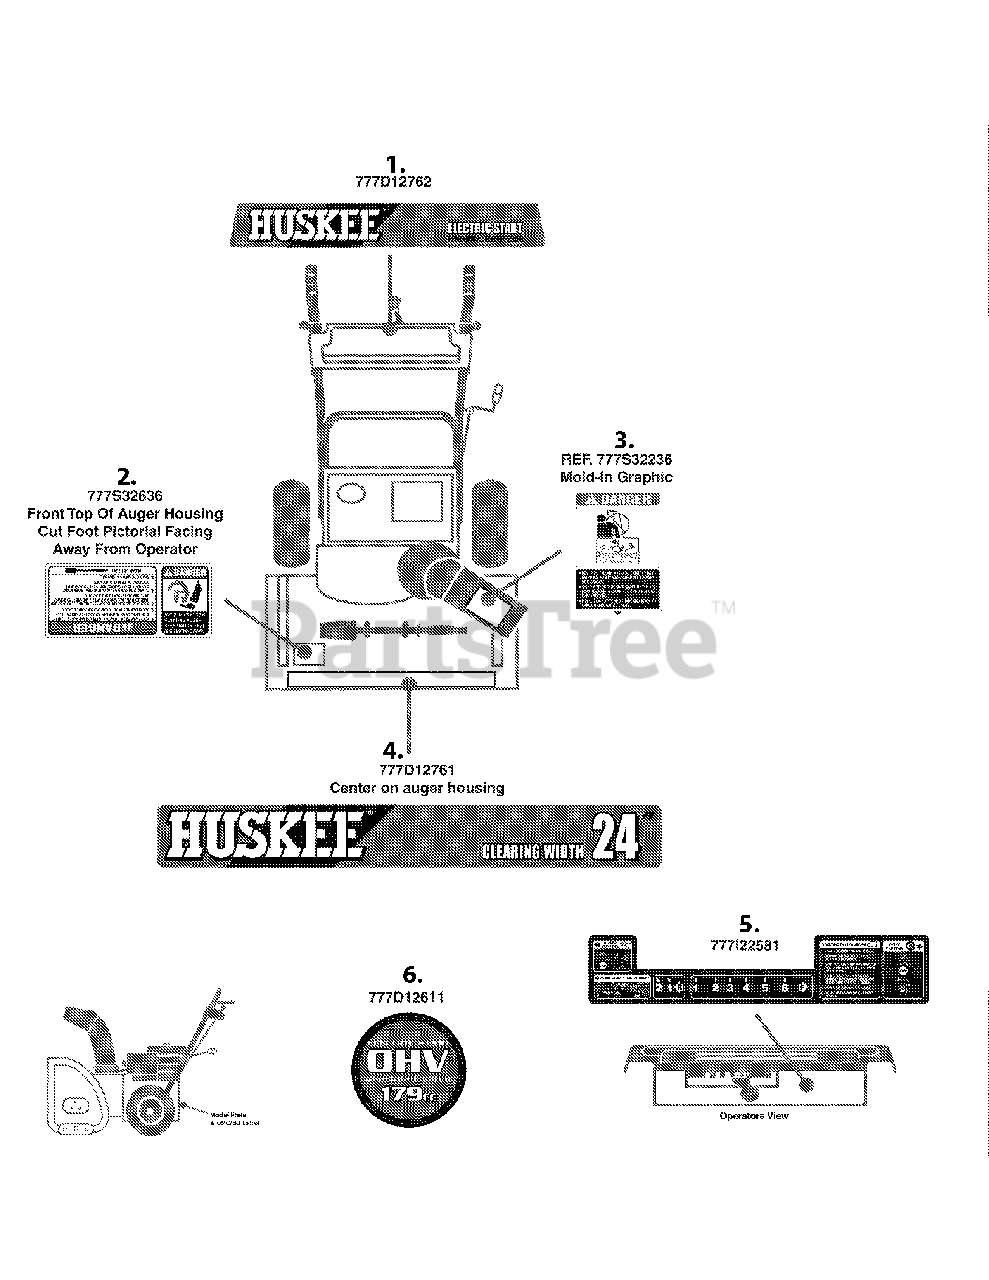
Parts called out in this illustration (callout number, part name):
1	LABEL:SNW:HNDLPANL:HUSK:6/2
2	LABEL:SNOW HOUSING
3	LABEL:SNOW CHUTE
4	LABEL:SNW:FRT/AUG:HUSK:24
5	LABEL-OPERATOR PAN
6	LABEL:ENG/SPN:OHV/ES/179
